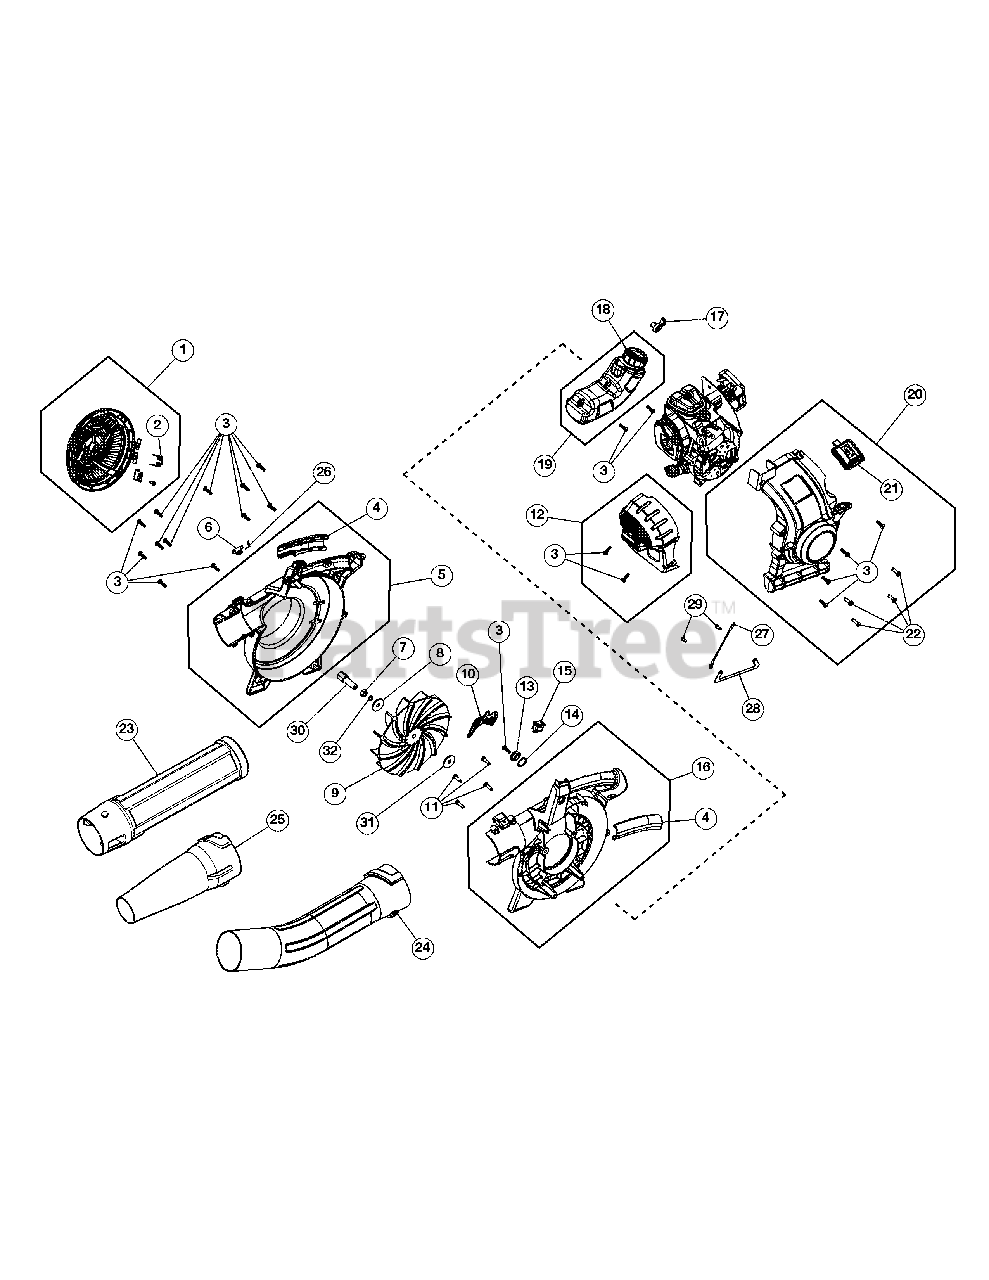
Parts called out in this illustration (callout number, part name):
1	Intake Cover Assembly
2	Spring
4	Handle Grips
5	Impeller Housing (Incl. 4)
6	Latch Tube
7	Nut
8	Washer
9	Impeller
10	Throttle Trigger
11	Screw
12	Muffler Cover (Incl. 3)
13	Inner Trigger Lock
14	Wavey Washer
16	Impeller Housing (Incl. 4)
17	Outer Trigger Lock
18	Fuel Cap
19	Fuel Tank Assembly (Incl. 18)
20	Engine Cover Assembly (Incl. 3, 21 & 22)
21	Spark Plug Cover
23	Upper Tube
24	Curved Lower Tube
25	Nozzle
26	Latch Spring
27	Wire Ground
28	Strap Ground
29	Screw
30	Adapter
31	Spacer
32	Bell/Lock Washer
